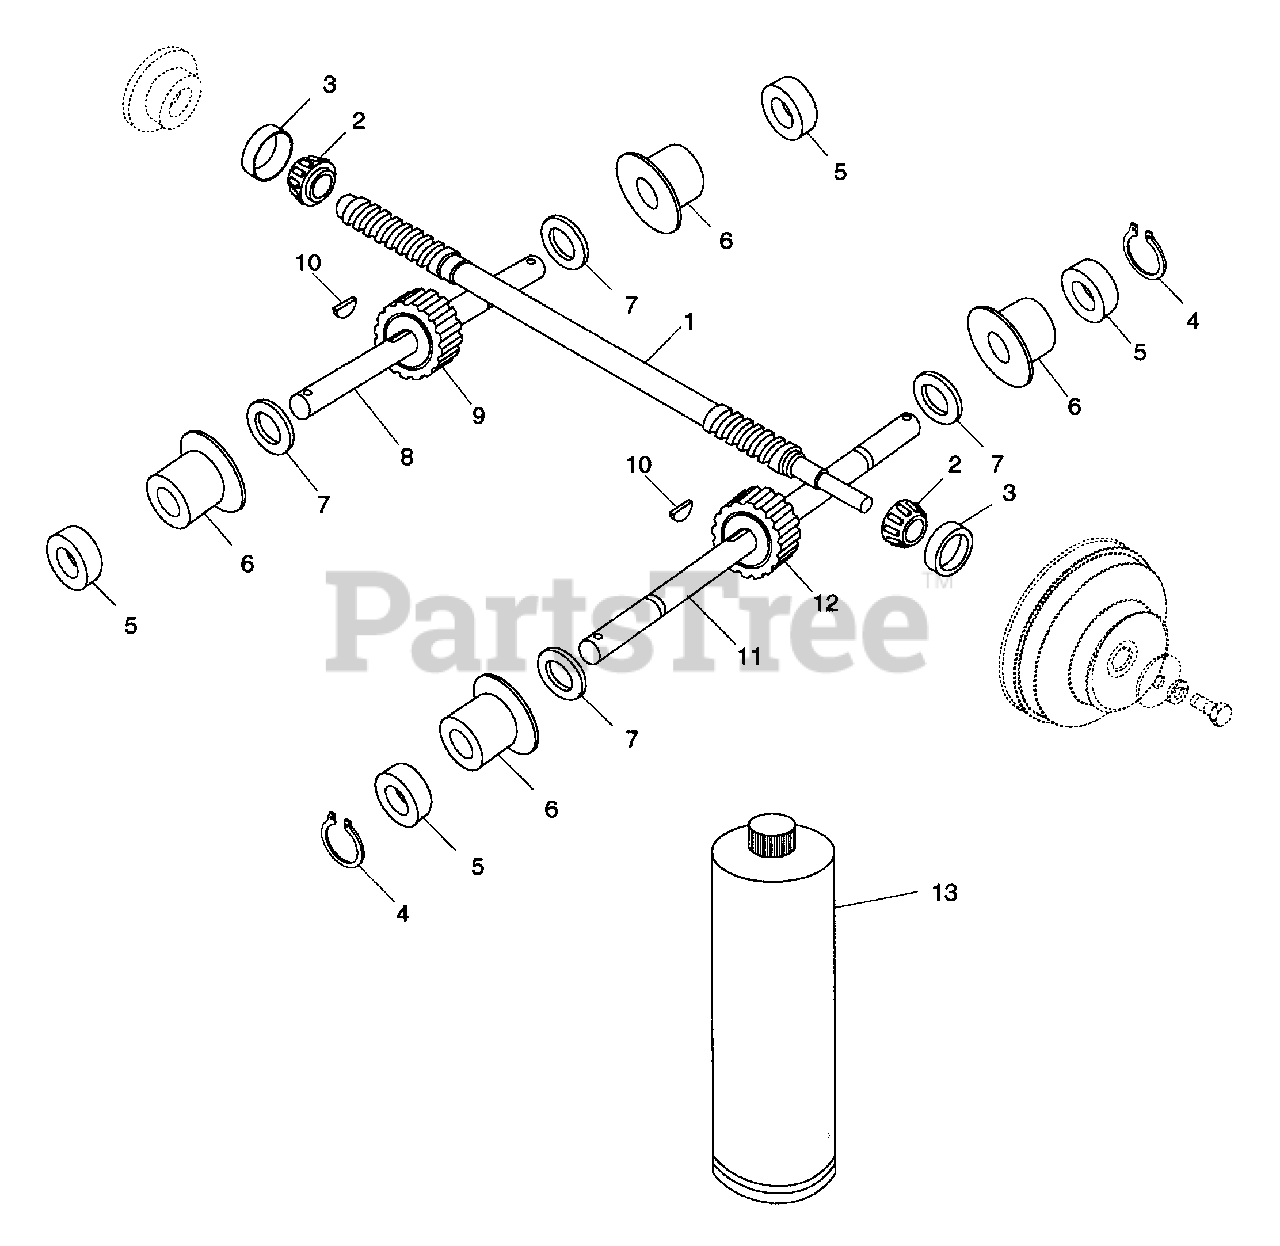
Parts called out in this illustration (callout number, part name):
1	WORM SHAFT
2	BRG-CONE .750X.61
3	BRG-CUP 1.781X.475
4	RG-RTNG .822X1.500X.050 TYP E
5	SEAL 1.000X1.312X.150
6	BSHG-FLG 1.000X1.125X1.875
7	WSHR-HDND-THRUST 1.00X1.55X.03
8	TINE SHAFT
9	WORM GEAR
10	KEY-WDRF .25X.875X.375 SAE A
11	WHEEL SHAFT
12	WORM GEAR 61
13	ARIENS 16 OZ.BOTTLE OF L2 LUBE
